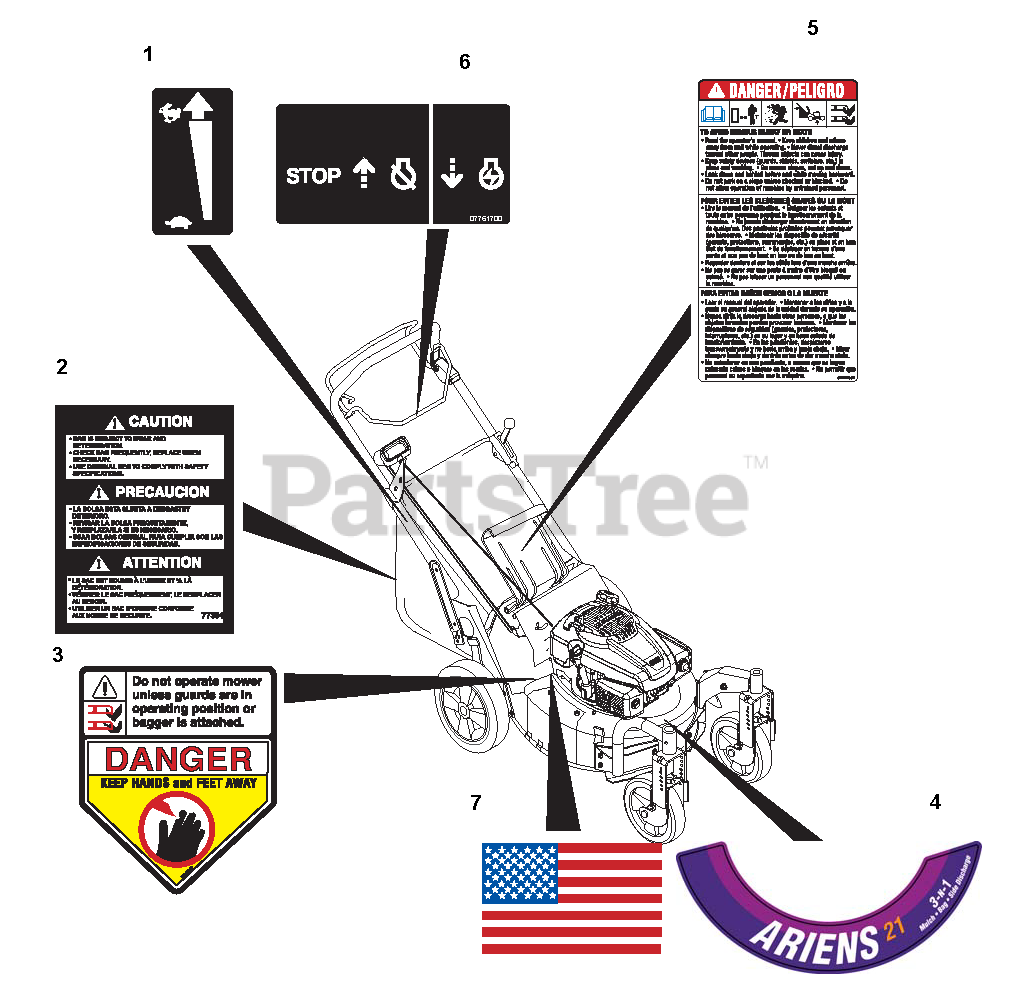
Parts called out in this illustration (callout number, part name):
1	DECAL-SPEED CONTROL
2	LABEL - BAGGER 21"
3	DECAL, CPSC DANGER
4	DECAL, ARIENS DECK
5	DECAL, BILINGUAL DANGER
6	DECAL - ENGINE CONTROL
7	DECAL, AMERICAN FLAG
